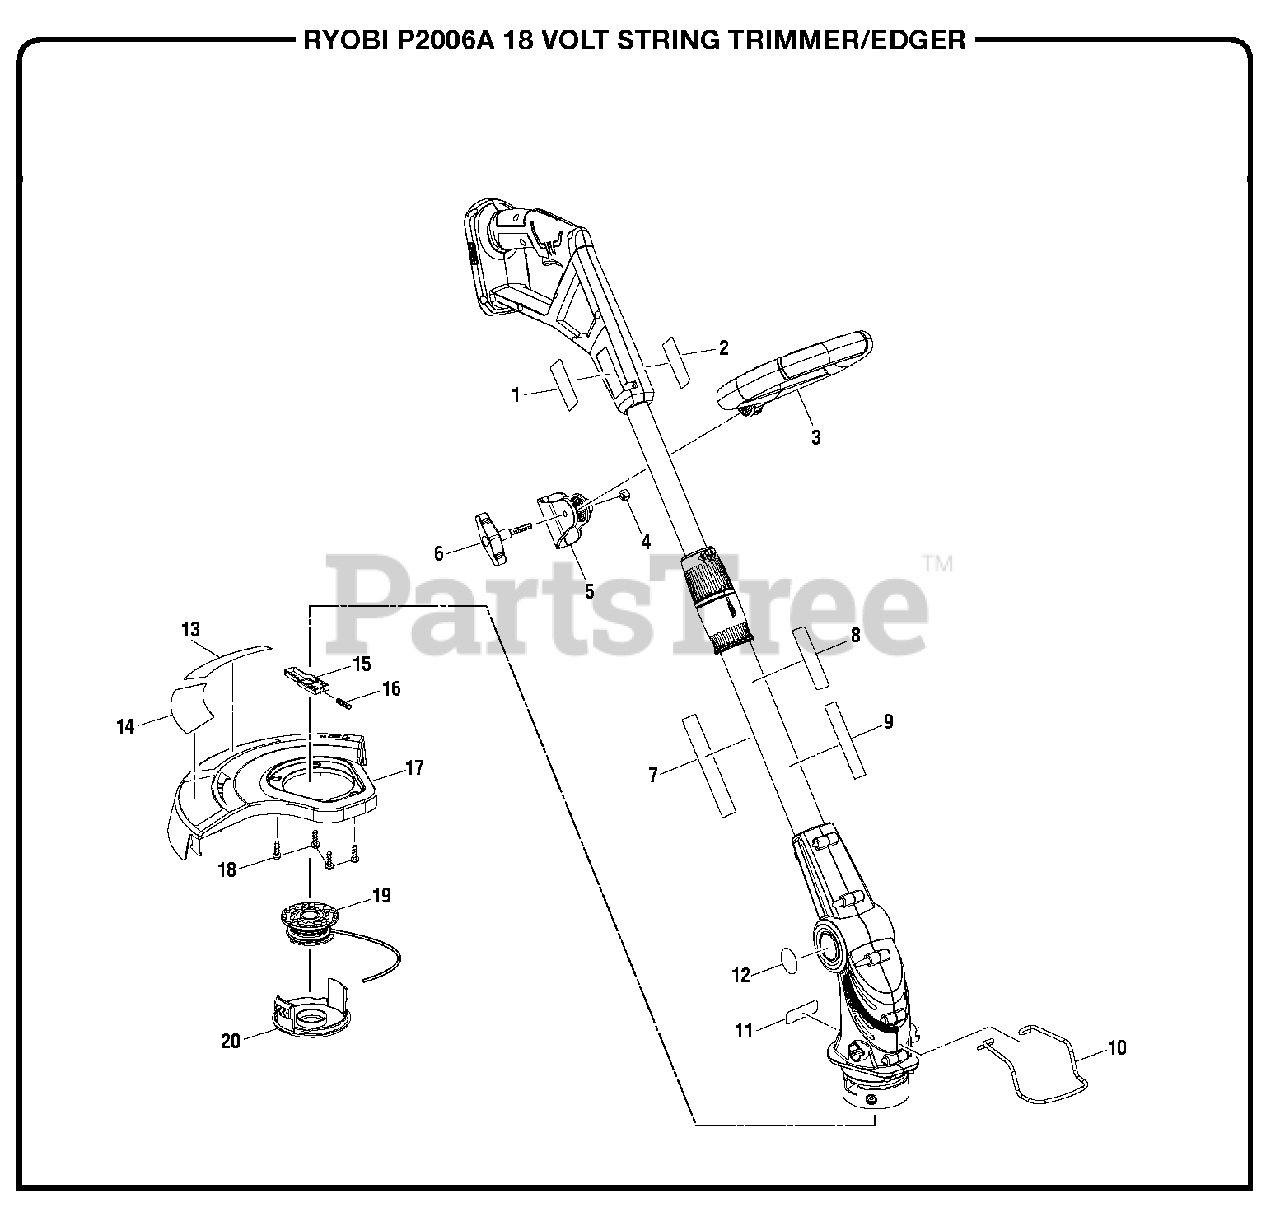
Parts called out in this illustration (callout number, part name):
1	Data Label
2	Logo Label (Handle)
3	Front Handle
4	Hex Nut (M6)
6	Knob Screw (M6)
7	Warning Label (Fr/Sp)
8	Warning Label (Icon)
9	18V Lithium-Ion Label
10	Edger Guide
11	Logo Label (Housing)
12	Pivoting Head Label
13	Auto Line Feed Label
14	Adjustable Cutting Width Label
15	Slider Assembly
16	Compression Spring
17	Grass Deflector Assembly
18	Screw (M4 x 12 mm)
19	Spool w/Line (AC14RSLA)
20	Spool Cap (AC14HCA)
